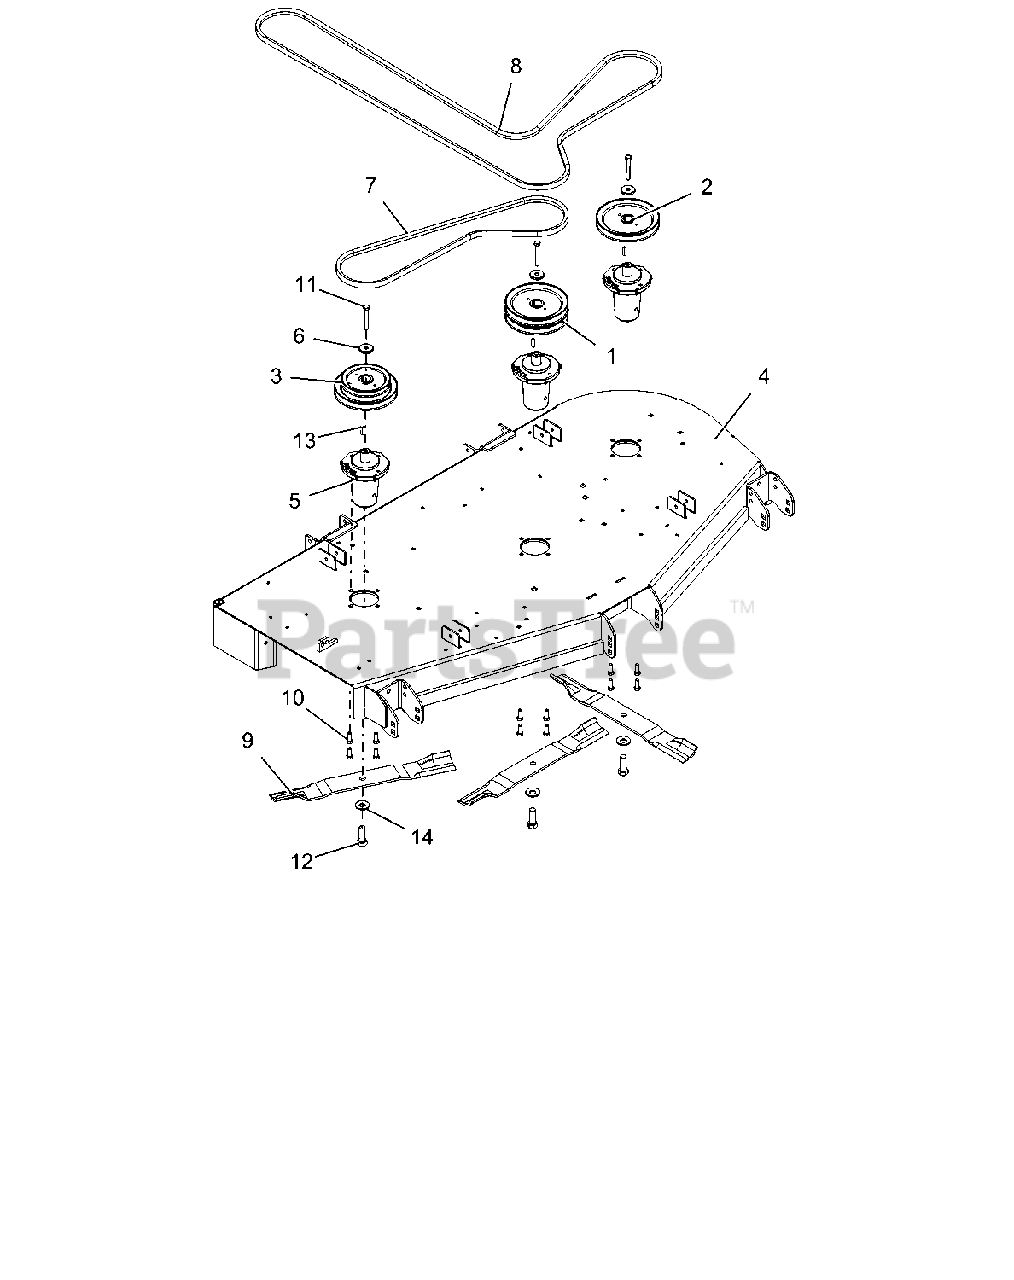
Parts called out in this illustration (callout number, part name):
1	PULLEY, DOUBLE-1"ID X 6.75"OD
2	PULLEY, V-1" ID X 6.75" OD
3	PULLEY, DBL-1"IDX6.75"&5.25"OD
4	60"SIDE DISCH DECK WMT W/SAFE
5	ASM, MAINT FREE SPINDLE
6	RETAINER, SHEAVE
7	V-BELT, B-COGGED
8	V-BELT, HB-WRAPPED
9	BLADE, MOWER (20.50")
10	BLT-HEX .38-16X1.0 GR8 YZ EP30
11	BLT-HEX .38-16X2.75 GR8 YWZC
12	BLT-HEX .62-18X1.75 GR8 YWZC
13	KEY, SQ .25X.25X1.00 RC 40-50
14	WSHR-BLVL .669X1.535X.138
